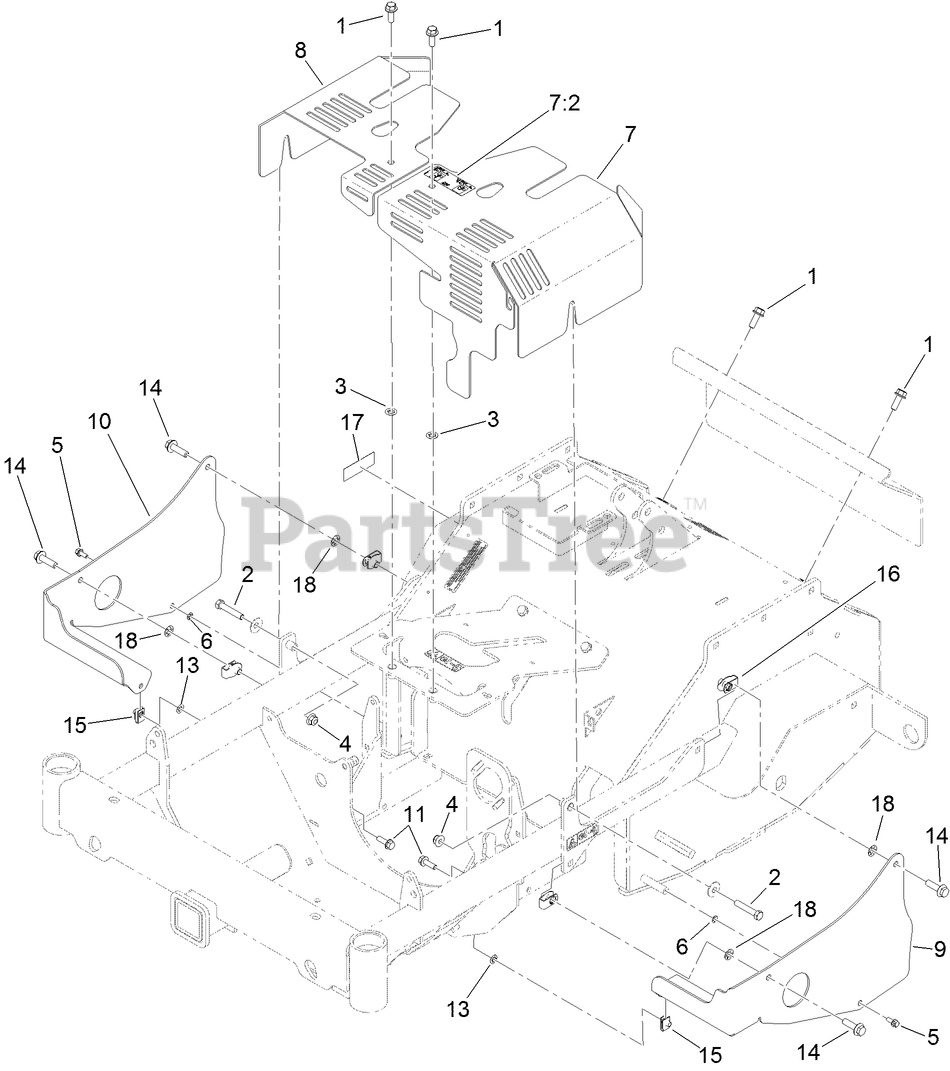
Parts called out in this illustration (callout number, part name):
1	SCREW-HHF
2	SCREW-HH
3	NUT-PUSH
4	NUT-HF, NI
5	SCREW-HHF
6	PUSHNUT-RETAINER, BOLT
7	HYDRO COVER ASM
7:2	DECAL-RELEASE, DRIVE
8	COVER-HYDRO
9	GUARD-CHAIN
10	GUARD-CHAIN
11	SCREW-HHF
13	RING-RETAINING, BOLT
14	SCREW-HHF
15	NUT-U
17	DECAL-SOUND
